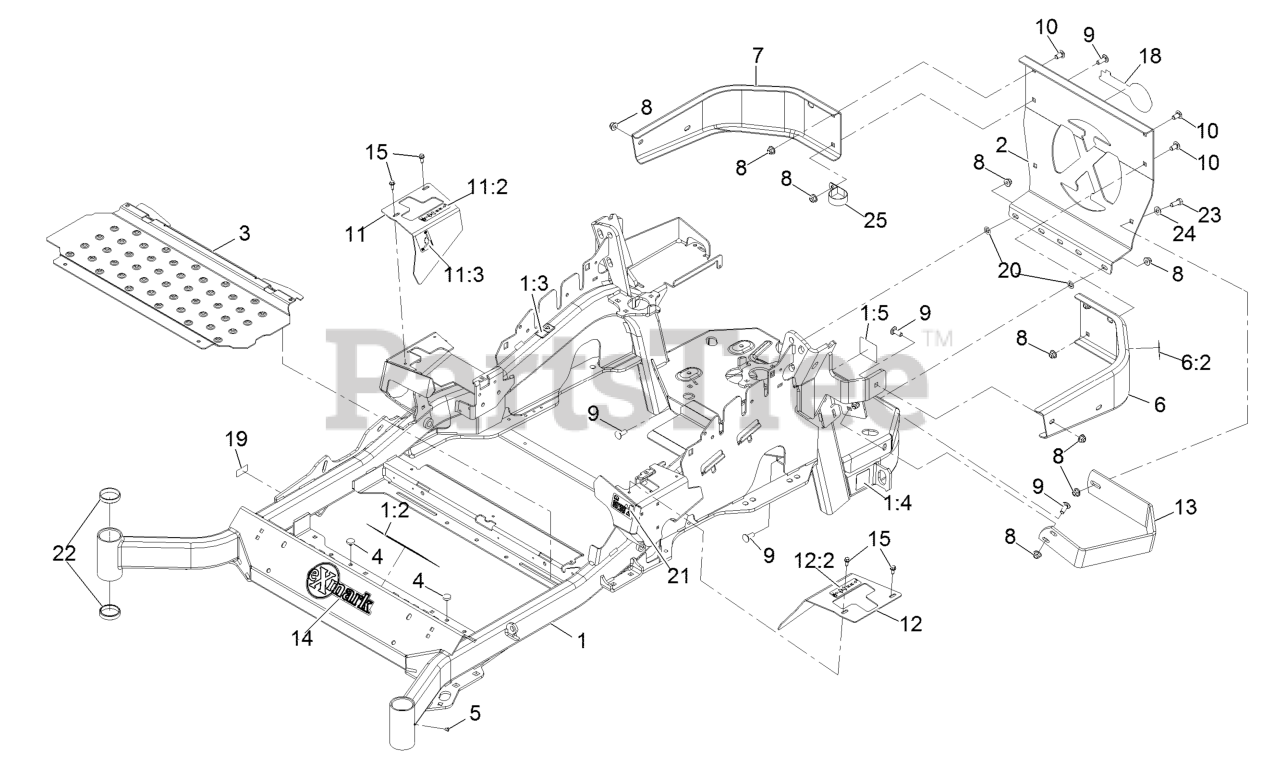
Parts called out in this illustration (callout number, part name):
1	Mainframe ASM
1:2	Decal-Danger
1:3	Decal-Warning
1:4	Decal-Hazard, Pinched Finger
1:5	Decal-Spark Arrester
2	Plate,Rear Guard
6	LH Bumper ASM
6:2	Decal-Warning
7	Bumper-RH
8	Nut-HF, NI
9	Screw-CARR
10	Screw-CARR
11	RH Motion Control Cover ASM
11:2	Decal-Control, Motion
11:3	Decal-Park Brake, CE
12	LH Motion Control Cover ASM
12:2	Decal-Control, Motion
13	Guard-Muffler
14	Decal-Exmark Logo
15	Screw-HWH
18	Decal-Exmark Logo
19	Decal-Patent
20	Nut-Push
21	Decal-Fuel Fill, CE
22	Cup-Bearing
23	Screw-HH
24	Washer-Flat
25	Clamp-R
